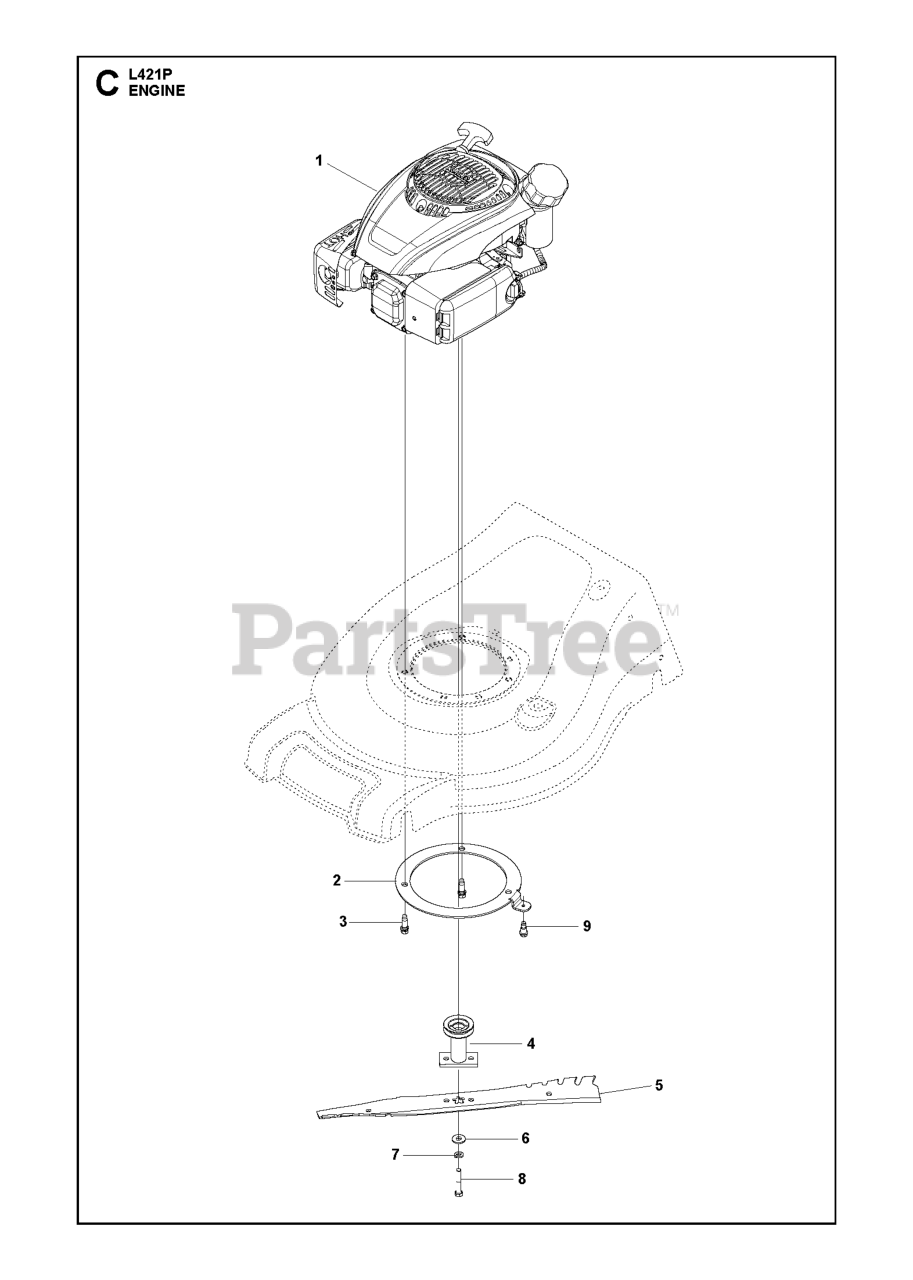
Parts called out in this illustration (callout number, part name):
2	MOUNTING PLATE BOTTOM ENGINE R
3	BOLT 3/8-16X1-1/8
4	ADAPTER.BLD.25M.2P.AW/RW/21EFF
5	BLADE.21.REAPER.WO/NOTCHES
6	WASHER,HARDEN
7	LOCKWASHER
8	BOLT.ENGINE.PULLEY
9	BOLT SHOULDER_1/4-20_TRILOB
